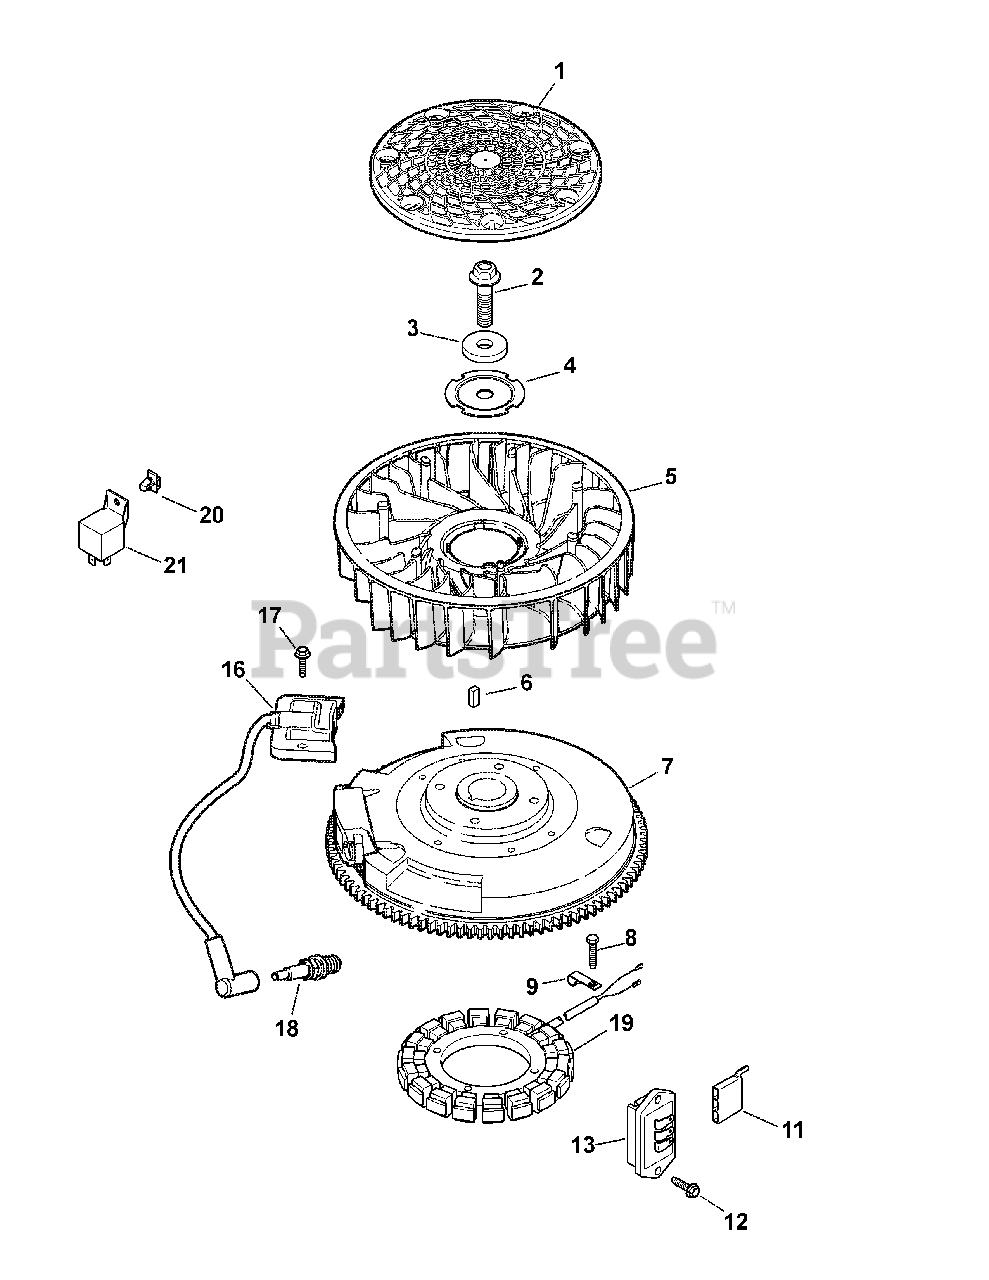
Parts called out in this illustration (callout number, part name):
2	Hex Flange Screw
4	Fan Mounting Plate
6	Straight Flywheel Key
7	Flywheel
8	Thd. Frm. Screw, M5 X 0.8 X 25
10	Fuse Block
12	Flg. Thd. Frm., M5 X .8 X 20
13	Regulator/Rectifier
14	Fuse Block
15	Fuse Block
16	Ignition Module (CDI Fixed)
17	Fuse Block
18	Spark Plug (Std)
19	Stator Assembly Kit
20	Push Wing Mount
